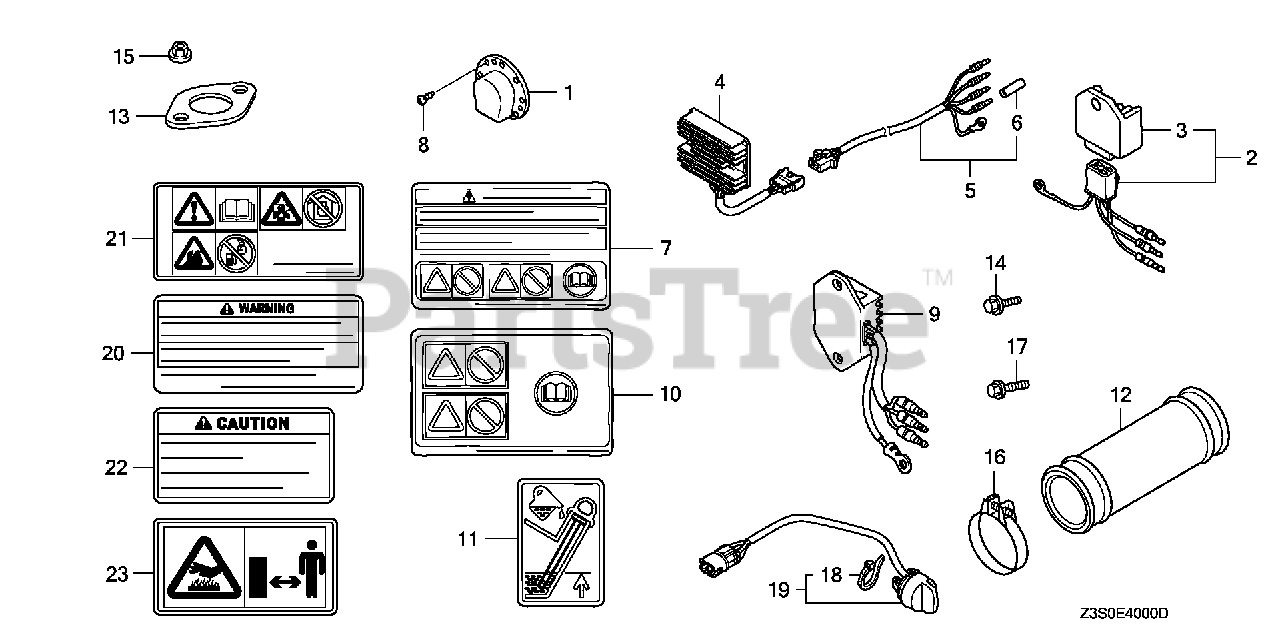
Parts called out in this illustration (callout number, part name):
1	CAP, MUFFLER
7	MARK, OPERATOR CAUTION (FRENCH)(MADE IN JAPAN)
8	SCREW, TAPPING (4X6) (TO INSTALL OPTIONAL SPARK ARRESTER)
20	MARK, OPERATOR CAUTION (FRENCH)(MADE IN JAPAN)
21	MARK, OPERATOR CAUTION (PICTOGRAPH)
22	MARK, EX. CAUTION (FRENCH)
23	MARK, EX. CAUTION (PICTOGRAPH)
